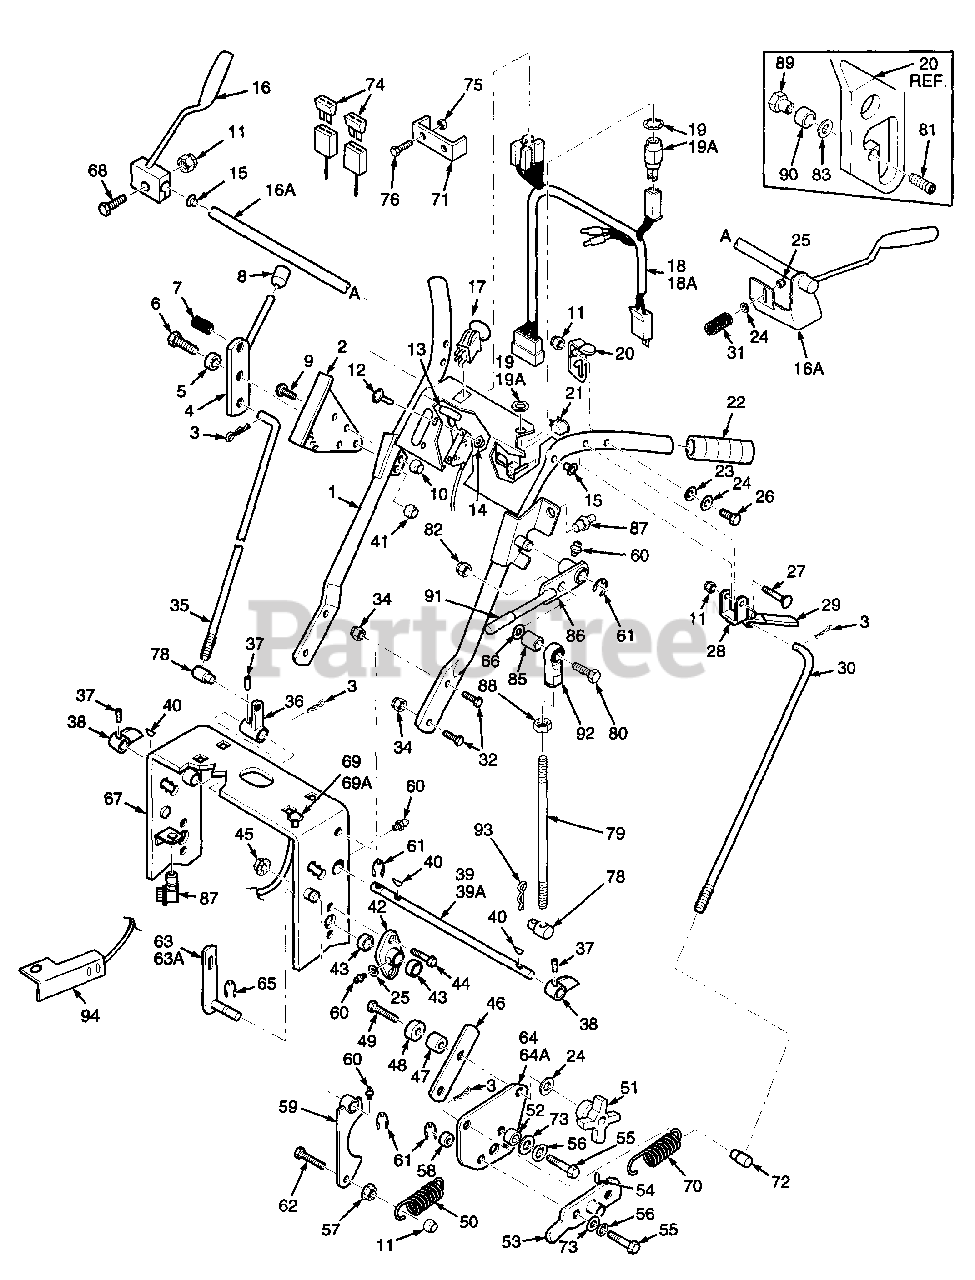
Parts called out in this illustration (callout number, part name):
1	Upper Handle Wlmt. W/Decals
2	Quadrant, Speed Control
3	Hairpin, .094 x 1.19
4	Lever, Speed Adjustment
5	Bushing, Speed Adjustment Lever
6	Hex Head Bolt, 3/8-16 x 1-1/2"
7	Ball Plunger
8	Knob, Speed Adjustment
9	Capscrew, 1/4-20 x 3/4" FHHS
10	Nut, 1/4-20 Elastic Stop
11	Nut, 5/16-18 Elastic Stop
12	Screw, #10-32 x 1/2" PW HD
13	Throttle Control
14	Nut, #10-32 Serr. Flange
15	Bushing
16	Handle, Oper. Presence - RH
16A	Handle, Oper. Presence - LH (20")
17	Switch, Elec. Clutch Eng.
18	Wire Harness, Manual Start
18A	Wire Harness, Electric Start
19	Key Switch, Manual Start
19A	Key Switch, Elec. Start
20	Neutral Latch - RH
20A	Neutral Latch - LH
21	Switch, Neutral Interlock
22	Grip
23	Washer, Curved Spring
24	Flat Washer
25	Lock Washer, 1/4" Int. Tooth
26	Hex Head Bolt, 5/16-18 x 2"
27	Hex Hd. Bolt, 5/16-18 x 2-1/2"
28	Lever, Steering Control
29	Grip, Steering Control
30	Rod, Steering Control
31	Spring, Handle Return
32	Capscr., 3/8-16 x 1" Ser. Flange
34	Nut, 3/8-16 Serr. Flange
35	Rod Speed Control
36	Bellcrank, Speed Control
37	Setscrew, 1/4-28 x 1/4"
38	Cam, Speed Control
39	Jackshaft, Speed Control
39A	Jackshaft, Speed Control
40	Key, 1/8 x 1/2" Woodruff
41	Nut, 3/8-16 Elastic Stop
42	Pivot, Pump Ctrl.
43	Bushing, 1/2" ID
44	Capscrew, 5/16-18 x 1" Serr. Flg.
45	Nut, 5/16-18 Serrated Flange
46	Bar, Speed Control
47	Spacer, Speed Ctrl. Bearing
48	Bearing, Speed Ctrl. Bellcrank
49	Hex Head Bolt, 5/16-18 x 1-3/4"
50	Spring, Return
51	Knob, 5/16-18
52	Bushing
53	Handle, Neutral Adj
54	Drive Pin, 5/32 x 7/8 Type U
55	HH Bolt, 5/16-18 x 3/4"
56	Lock Washer, 5/16
57	Nut, 5/16-18 Serr. Flange
58	Bearing, Ball Neutral Return
59	Cam, Neutral
60	Grease Fitting, 1/4-28 UNF
61	Retaining Ring, 5/8 Ext. "E"
62	Hex Head Bolt, 5/16-18 x 1"
63	Shaft, Pump Control - LH
63A	Shaft, Pump Control - RH
64	Bellcrank, Pump Control - LH
64A	Bellcrank, Pump Control - RH
65	Retaining Ring, 1/2 Ext. "E"
66	Flat Washer, 15/16 x 25/64 x 12 ga.
67	Deck, Engine
68	Hex Head Bolt, 5/16-18 x 1-1/4"
69	Choke Control
69A	Choke Control
70	Spring, Return
71	Fuse Holder
72	Swivel Joint, Steering Rod
73	Flat Washer (.344 x .688 x .065)
74	Blade Fuse, 20A
75	Nut, #10-32 Elastic Stop
76	Screw, #10-32 x 1-1/2" Phillips
78	Swivel Joint
79	Rod, Brake Lever
80	Hex Hd. Bolt, 3/8-16 x 1 3/4
81	Soc. Hd. Capscrew, #8-32 x 1/2
82	Nut, 3/8-16 Elastic Stop
83	Washer #8-.170 x .375 x .032
85	Spacer
86	Parking Brake Lever with Grip
87	Switch, Parking Brake
88	Nut, 3/8-24
89	Bushing, bearing Retainer
90	Bearing, Neutral Lock
91	Grip, Parking Brake
92	Ball Joint, RH Thread
93	Hairpin, .094 x 1.62
94	Bracket, Choke Mtg.
